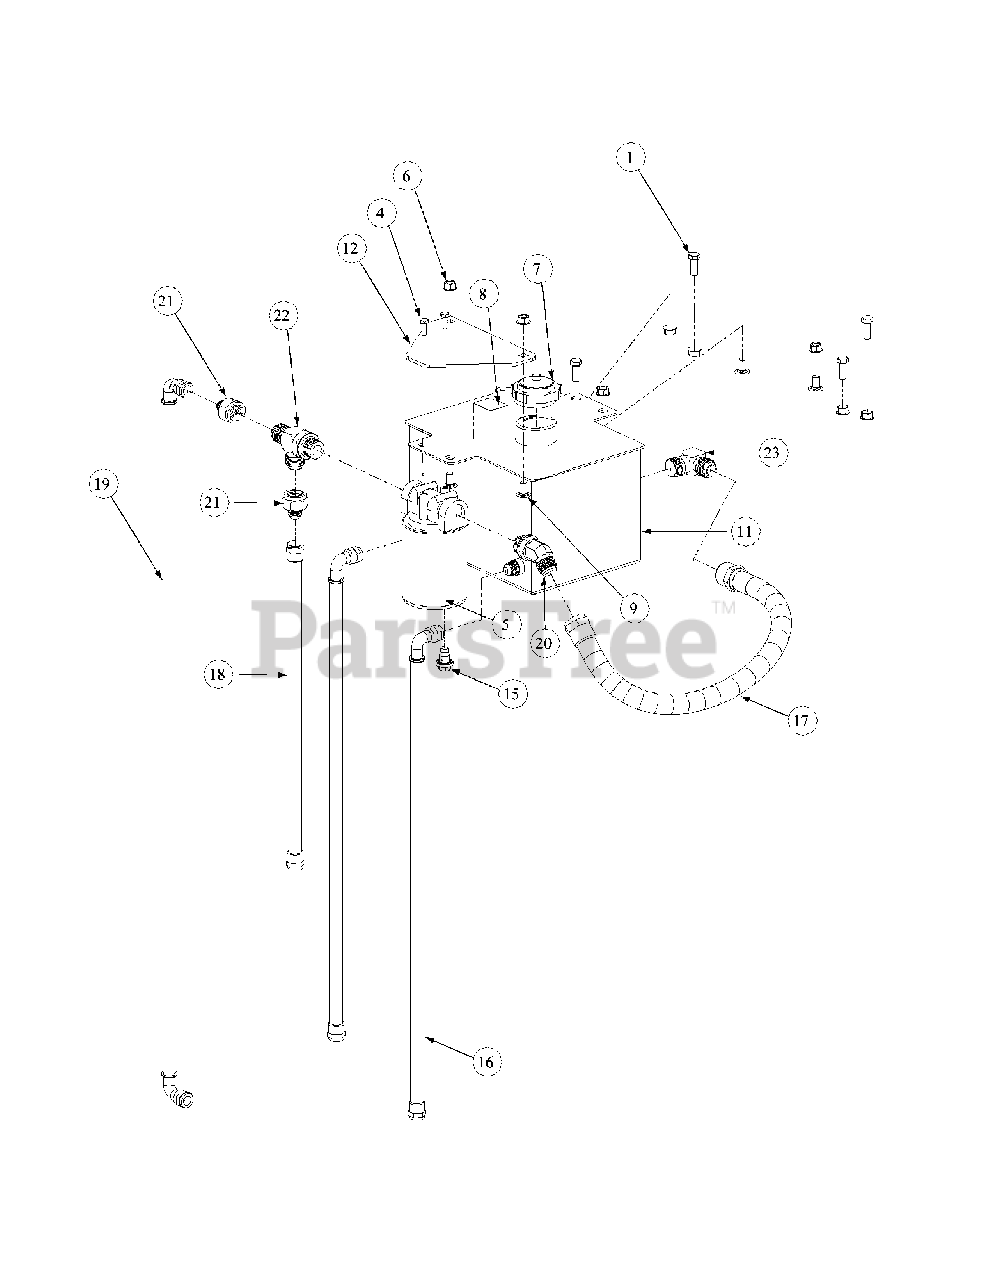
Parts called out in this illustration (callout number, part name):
1	Hex Cap Screw, 3/8-16, 1
4	Hex Cap Screw, 1/4-20, .75
5	Filter Head 3/4
5	33 Micron Filter
6	Hex Nut Flange Lock, 3/8-16
7	Cap, Hydro Oil Tank
8	Decal Oil Only 20W50
9	Carriage Bolt, 3/8-16 x .75 LG.
11	Hydraulic Tank Assembly
12	Mounting Plate Oil Filter
15	Oil Pan Drain w/ Seal and Plug
16	Gearbox to Tank Hose Assembly
17	Tank to Filter Hose Assembly
18	Filter to Left Hand Pump Hose Assembly
19	Filter to Right Hand Pump Hose Assembly
20	Connector, 3/4 x3/4
21	Adapter 3/4 x 1/2
22	Fitting Tee, 3/4 x 3/4 x 3/4
23	Fitting Elbow, 1/2 x 1/2
